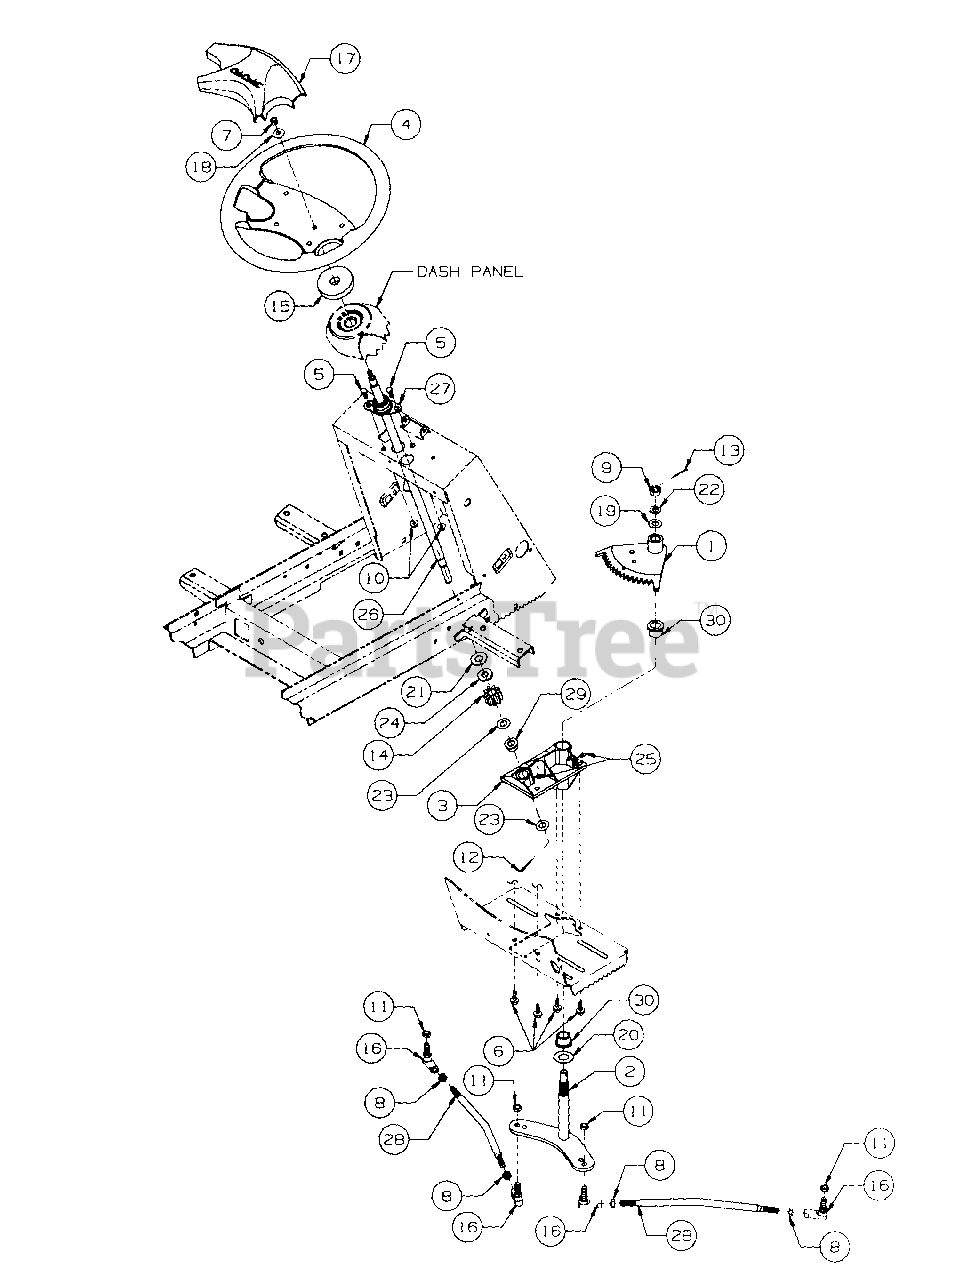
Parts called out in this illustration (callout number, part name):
1	Segment Assy, 1ST - Steering
2	Arm Assy, Lower Steering
3	Housing Assy, Steering
4	Wheel, Steering
5	Screw, Hex Cap, 1/4-20 x .62, GR5
6	Screw, Hex Wash Hd-TPTT, 5/16-18 x .75 Lg
7	Nut, Hex Center Lock, 5/16-24
8	Nut, Hex Jam, 3/8-24 GR5
9	Nut, Hex Slotted, 1/2-20 GR5
10	Nut, Hex Flange Lock, 1/4-20
11	Nut, Hex Lock, 3/8-24 GR5
12	Pin, Cotter, 1/8 Dia x 1
13	Pin, Cotter, 3/32 Dia x 1.25
14	Pinion, Steering
15	Gasket, Steering
16	Joint, Ball, 3/8-24
17	Insert, Steering Wheel
18	Washer, Bell, .340 x .88 x .06 Thk
19	Washer, Flat, .510 x 1 x .06 Thk
20	Washer, Flat, .760 x 1.5 x .03 Thk
21	Washer, Flat, .56 x 1 x .04 Thk
22	Washer, Lock, 1/2
23	Washer, Flat, .531 x 1 x .027 Thk
24	Washer, Rubber Flat, .50 x 1.12 x .125 Thk
25	Fitting, Lube, 3/16 Drive Type
26	Shaft, Steering
27	Bearing, Flange
29	Bearing, Flange, .503 ID
30	Bearing, Bronze Flange, .75 ID
